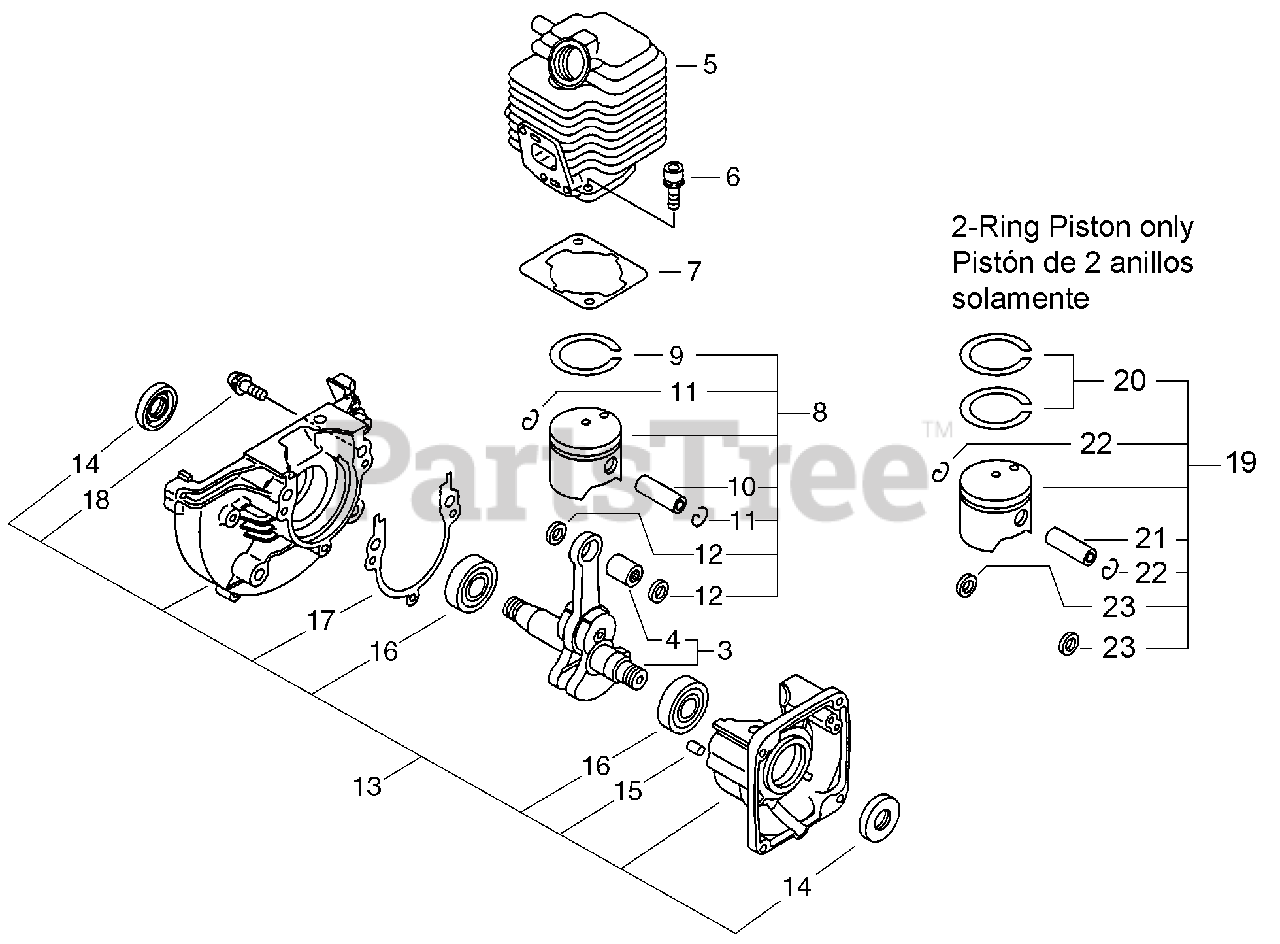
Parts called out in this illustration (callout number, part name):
3	CRANKSHAFT ASSY
4	BEARING, NEEDLE - 8
5	CYLINDER
6	SCREW - 5X22
7	GASKET, CYLINDER
8	PISTON KIT
9	RING, PISTON
10	PIN, PISTON
11	RING, RETAINING
12	SPACER, PISTON
13	CRANKCASE KIT
14	SEAL, OIL
15	PIN - LOCATING
16	BEARING, BALL - 6201
17	GASKET, CRANKCASE
18	SCREW - 5X28
19	PISTON KIT
20	RING, PISTON
21	PIN, PISTON
22	RING, RETAINING
23	SPACER, PISTON
